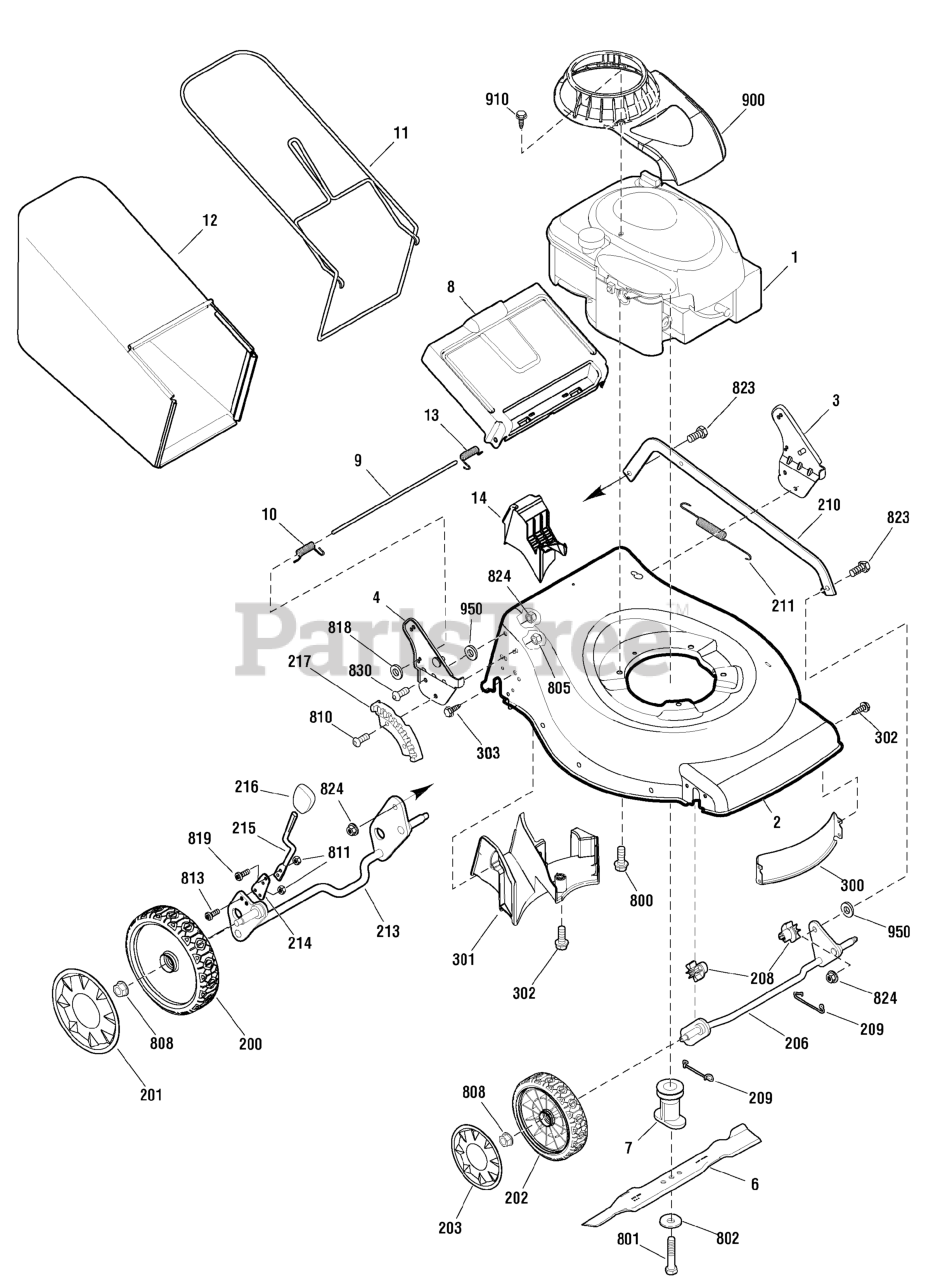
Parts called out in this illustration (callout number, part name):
1	* ENGINE, 5.5GT Briggs & Stratton
2	MOWER HOUSING
3	BRACKET ASSEMBLY, Left Handle
4	BRACKET ASSEMBLY, Right Handle
6	BLADE, 16 in
7	BLADE ADAPTER ASSEMBLY
8	DOOR, Rear
9	ROD, Rear Door
10	SPRING, Torsion Rear Door, Right
11	FRAME ASSEMBLY
12	BAG ASSEMBLY
13	SPRING, Torsion Rear Door, Left
14	MULCH PLUG
200	WHEEL, Rear
201	HUBCAP, Rear
202	WHEEL, Front
203	HUBCAP, Front
206	CROSSBAR ASSEMBLY, Front
208	BUSHING, Front Crossbar
209	SPRING, Clip Crossbar
210	LINK, Single Lever
211	SPRING, Extension
213	REAR CROSSBAR
214	SPRING, Adjuster
215	LEVER, Height Adjustment
216	KNOB, Adjuster
217	BRACKET, Height Adjuster
300	BAFFLE, FRONT, 16"
301	BAFFLE, REAR, 16"
302	SCREW, Pan Head, Taptite, 1/4-20 x 1/2
303	SCREW, Pan Head, 1/4-15 x 5/8
800	CAPSCREW, Hex Head, 3/8-16 x 1
801	BOLT, Blade, 3/8-24 x 2
802	WASHER, Belleville
805	NUT, Nylock, M8 x 1-1/4
808	NUT, Flange, 3/8-16
810	BOLT, Hex Key Head
811	NUT, Nylock
813	SCREW, Torx Head, M5 x .8 x 14mm
818	PUSHNUT, 1/4
819	SCREW, Torx Head, M5 x .8 x 12.5mm
823	BOLT, Shoulder, 5/16-18 x 1
824	NUT, Flange, 5/16-18
830	CAPSCREW, 5/16-18 x 3/4
900	SHROUD
910	CAPSCREW, Hex Washer Head
950	WASHER, Flat, .34ID
1000	DECAL KIT
